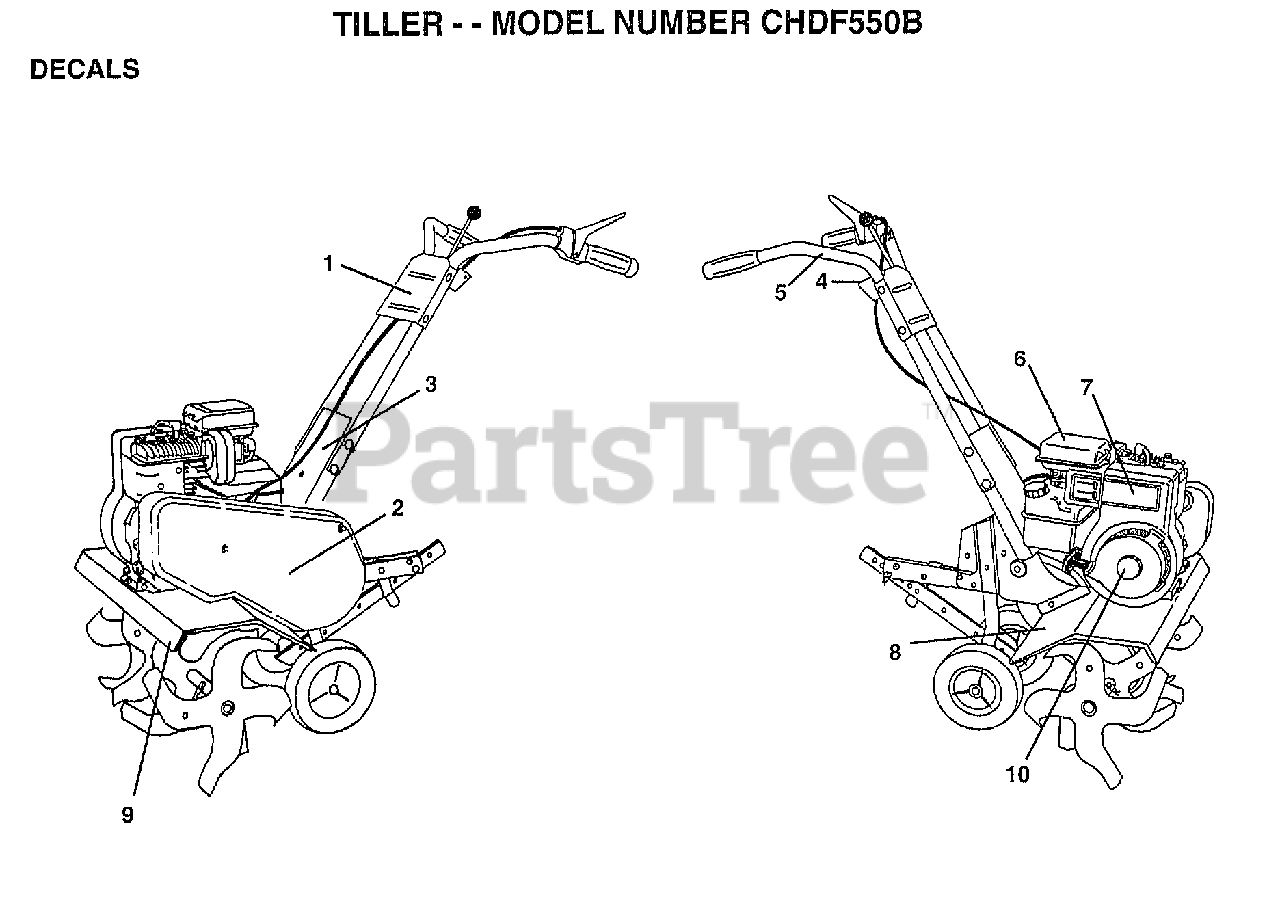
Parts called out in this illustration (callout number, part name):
1	"DECAL PANEL,CTRL"
2	"DECAL GUARD,BELT"
3	"DECAL PANEL,FORWD"
4	DECAL.PNL.CTRL.ES
5	DECAL.HAND.PLACE
6	DECAL.CAUTION.E/S
7	DECAL, BRIGGS & STRATTON
8	DECAL.WARN.ROT.TI
9	"DECAL SHIELD,TINE"
10	DECAL, 5 HP
